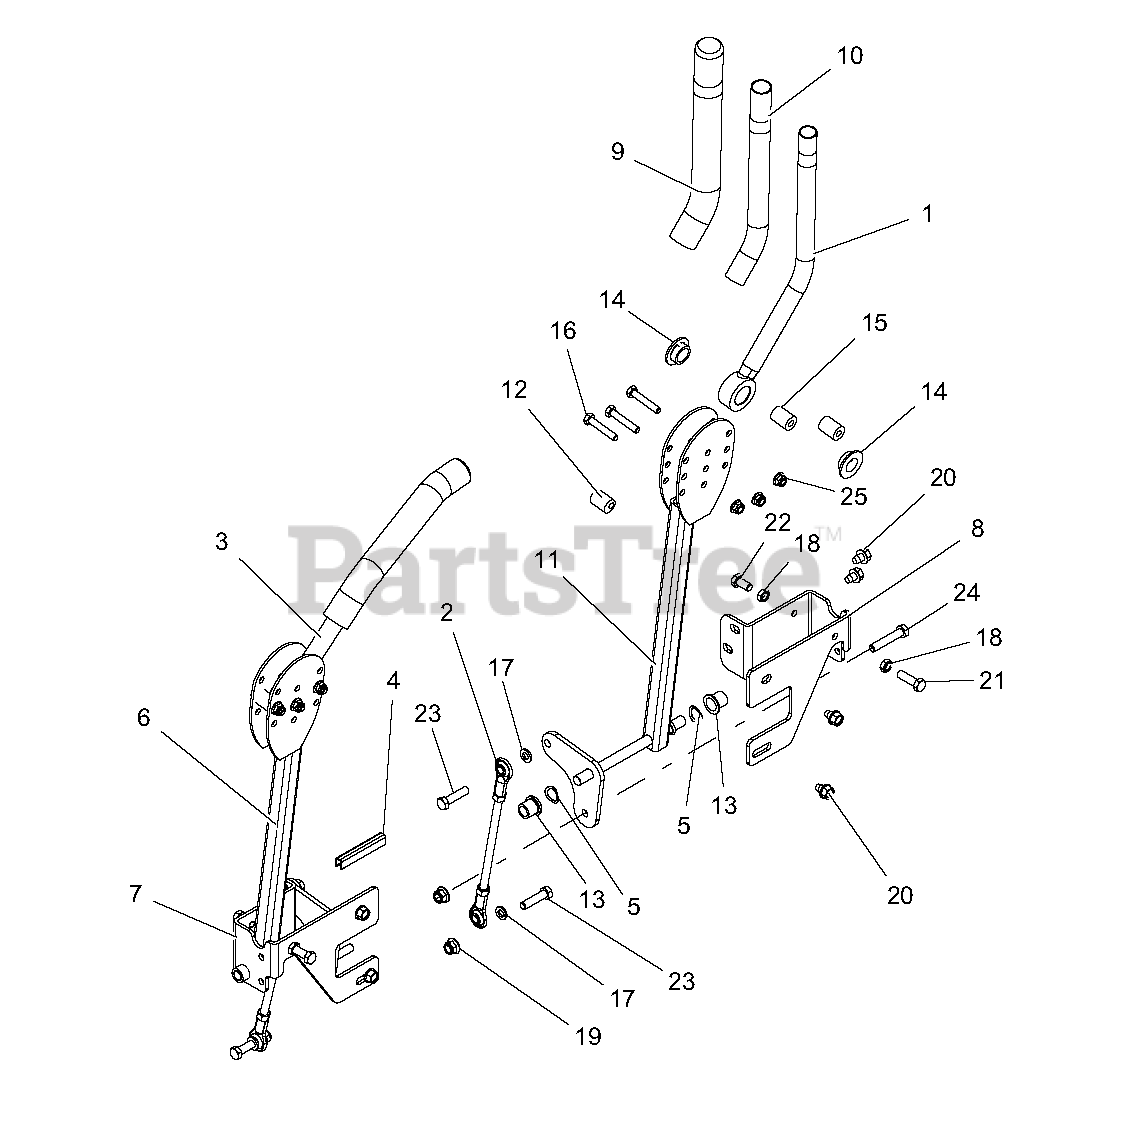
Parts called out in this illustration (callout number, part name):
1	WLDMT, LH HANDLE
2	ASM, STEERING LINKAGE
3	WLDMT, RH HANDLE
4	STRIP, COWL - 1.50 LG
5	WAVE WASHER .640 X .875 X .125 FH
6	WLDMT, RH PT/PT100 CONTROL ARM-BLACK
7	BRKT, RH STEERING STOP-RED
8	BRKT, LH STEERING STOP-RED
9	GRIP, HANDLEBAR
10	TUBE, .88ID X 1.00OD X 10.25
11	WLDMT, LH PT/PT100 CONTROL ARM-BLACK
12	BSHG, ECCENTRIC .31 X .75 X .97
13	BSHG, FLANGE .515 X .750 X .745 X 1.00 NYLON
14	BSHG, FLANGE .762 X 1.48 X .44 NYLON
15	SPACER, .328 X .76 X 1.01
16	@BLT-HEX .31-18X1.75 GR5 YWZC
17	@WSHR-LK .38X.094 REG YWZC
18	NUT, JAM .375-16 YWZC
19	@NUT-LK-NYL-FLG .38-16 YWZC
20	SCR-TAP .38-16X.50 HWH TR YWZ
21	BLT-HEX .38-16X1.25 GR5 YWZC
22	BLT-HEX .38-16X.75 GR5 YWZC
23	BLT-HEX .38-16X1.50 GR5 YWZC
24	BLT-HEX .38-16X2.0XGR5 FTD YWZC
25	@NUT-LK-NYL-FLG .31-18 YWZC
